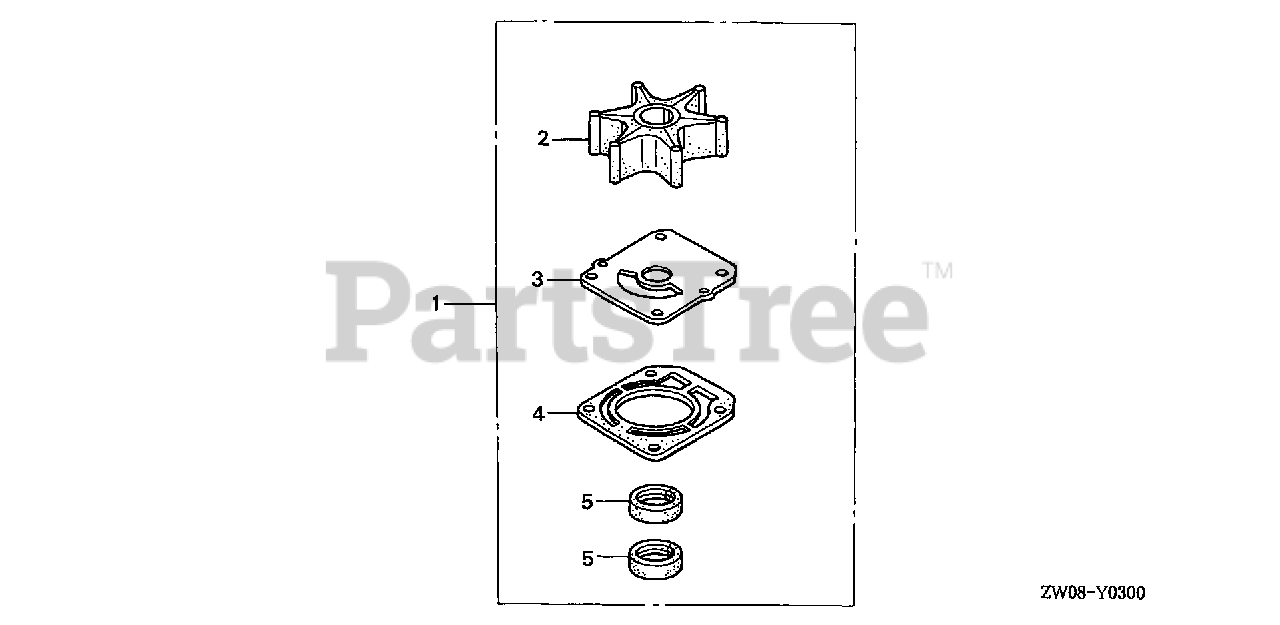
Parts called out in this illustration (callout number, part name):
1	IMPELLER KIT, WATER PUMP Use up to Frame SN 1300340.
2	IMPELLER, PUMP
3	GASKET B, IMPELLER
4	GASKET, WATER PUMP
5	SEAL, WATER (23X36X6) Use up to Frame SN 1300340.
